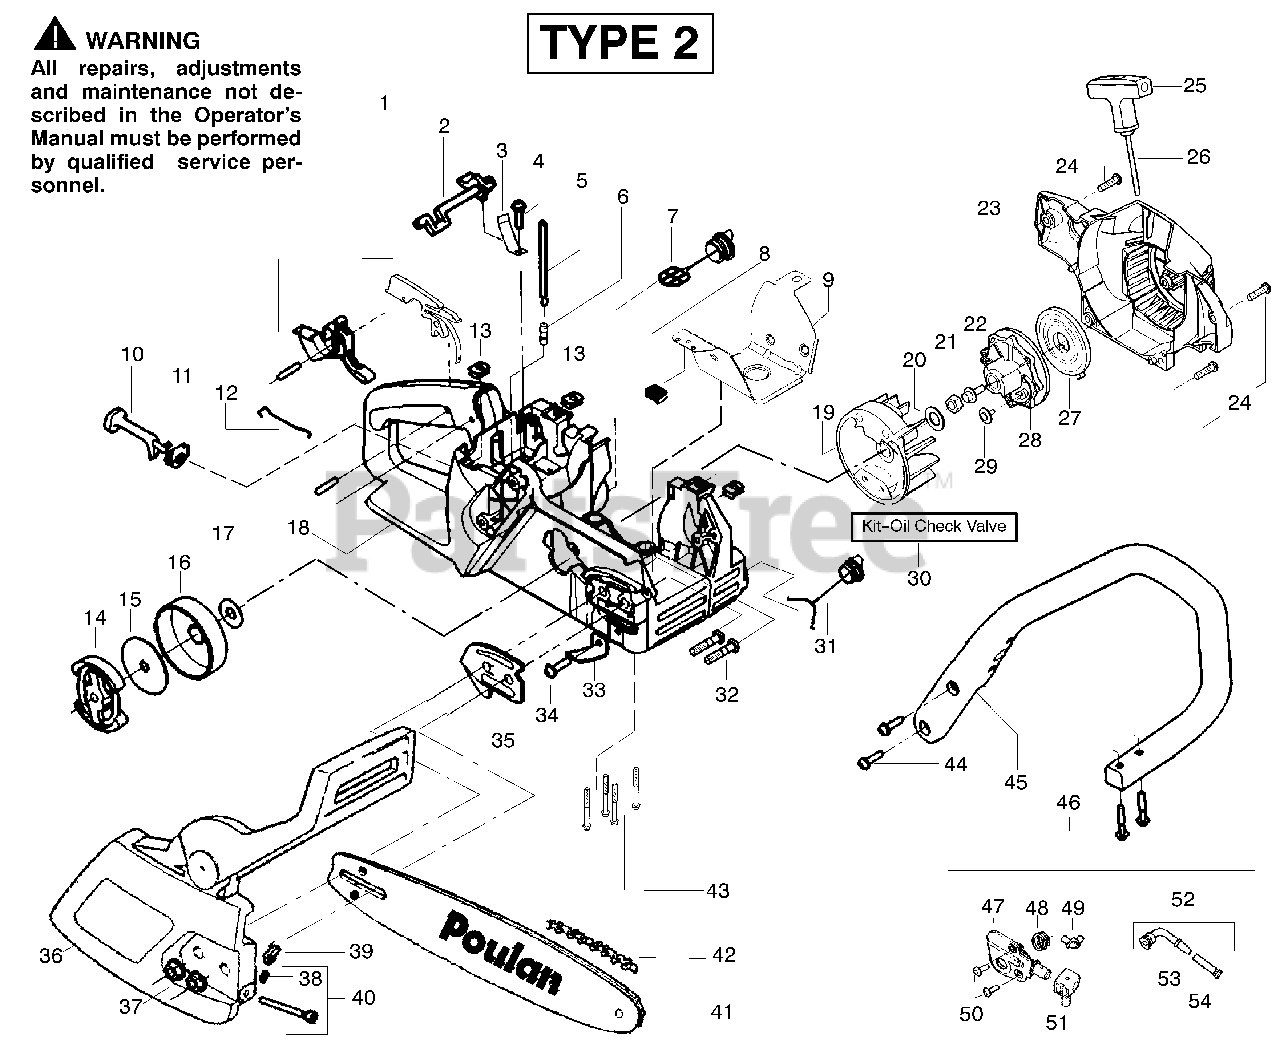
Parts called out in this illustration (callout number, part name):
1	Kit-Trigger & Lockout
2	Lever-Switch
3	Spring-Switch
5	Kit-Fuel Line
6	Fitting - Fuel Line
7	Assy-Fuel Cap w/ret.
8	Clip - "U"
9	Shield - Heat
10	Lever-Choke
11	Grommet-Choke Lever
12	Wire-Throttle
13	Nut-Speed
14	Assy.-Clutch
15	Washer-Clutch
16	Assy-Drum W/Brg.
17	Washer - Thrust
18	Kit-Chassis Assy.
19	Assy-Flywheel
20	Washer-Flywheel
21	Nut-Flywheel
23	Housing-Fan
25	Handle-Starter
26	Kit-Rope
27	Spring-Starter
28	Pulley-Starter
30	Kit-Oil Check Valve
31	Assy-Oil Cap
32	Bolt - Bar
33	Chain Catcher
35	Plate-Bar Mounting
36	Assy.-Chain Brake
37	Nut-Bar Mounting
38	Retainer-Bar Adjust
39	Pin-Bar Adjust
40	Kit-Bar Adjust
41	Bar- 18"
42	Chain- 18"
45	Handle-Front
47	Kit-Oil Pump
48	Gear-Worm Spring
49	Elbow-Oil Pickup
51	Block-Seal
52	Assy-Oil-Pickup
53	Pickup-Oiler
54	Filter-Oil
